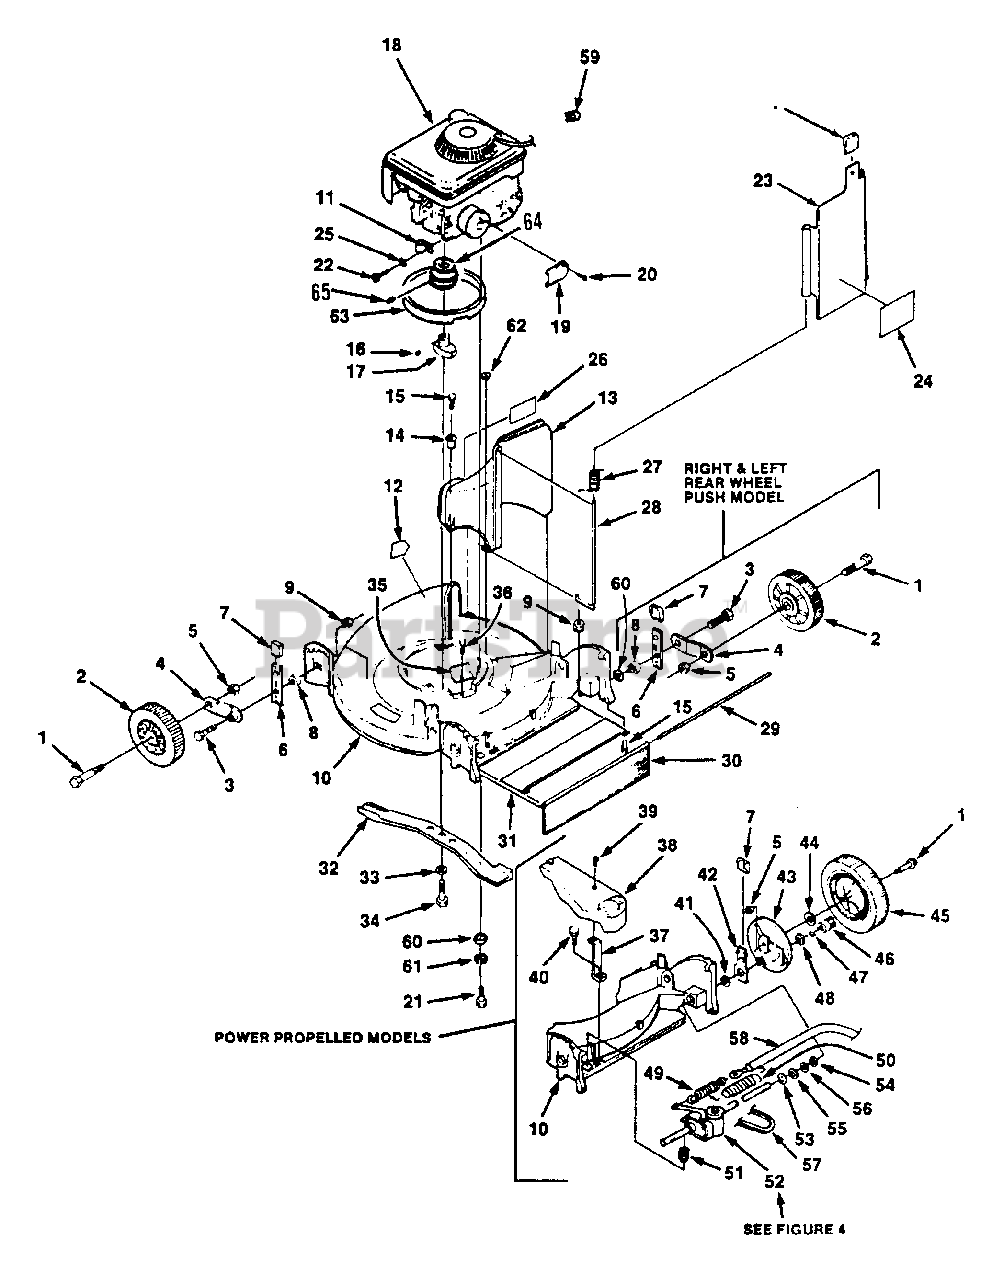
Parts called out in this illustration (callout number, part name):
1	AXLE ASSY
2	WHEEL ASSY
3	BOLT - 5/16 X 18
4	ARM - WHEEL ADJUSTING
5	NUT - 3/8-24
6	INDEXING ASSY
7	KNOB
8	SPACER
9	NUT - 5/16-18 -- FLANGE
10	DECK - 21"
11	CLAMP
12	LABEL - WARNING
13	CHUTE, DISCHARGE
14	EYELET
15	SCREW - 1/4-20 X 3/4"
16	KEY - 5/8 X 5/32
17	ADAPTOR, BLADE
18	ENGINE, 4 H.P. (4-CYCLE)
19	DEFLECTOR, MUFFLER
20	SCREW - 8-32 X 3/8"
21	SCREW - 3/8-16 X 1 1/2"
22	SCREW - 1/4-20 x 1/2"
23	DOOR, CHUTE
24	LABEL - DOOR
25	LOCKWASHER - 1/4"
26	LABEL - GASAHOL
27	SPRING
29	ROD, DRAG FLAP
30	FLAP, DEBRIS
31	COVER - REAR
32	BAR, CUTTER - 21"
33	LOCKWASHER - 7/16"
34	BOLT, SHOULDER
35	COVER, BELT
36	SCREW - 1/4-20 x 1/2"
37	SUPPORT
38	COVER, DRIVE
39	SCREW - 1/4-20 X 3/4"
40	SCREW - 10-16 X 1/2"
41	SPACER, HGT. ADJ.
42	SPRING, INDEX
43	DRIVE WHEEL SUPPORT
44	WASHER
45	DRIVE, WHEEL
46	PINION - LEFT HAND
47	PAWL, PINION
48	WASHER
49	SPRING, TRACTION LEVER
50	COVER, SPRING
51	SPRING
52	GEAR REDUCER ASSY
53	RING
54	WASHER
55	WASHER
56	SHIM
57	BELT, DRIVE
58	CABLE, TRACTION
59	GUIDE, ROPE
60	WASHER - 5/16"
61	LOCKWASHER - 5/16"
62	WASHER - 1/4"
63	RING, ENGINE
64	2-SPEED PULLEY
65	SCREW - SET
